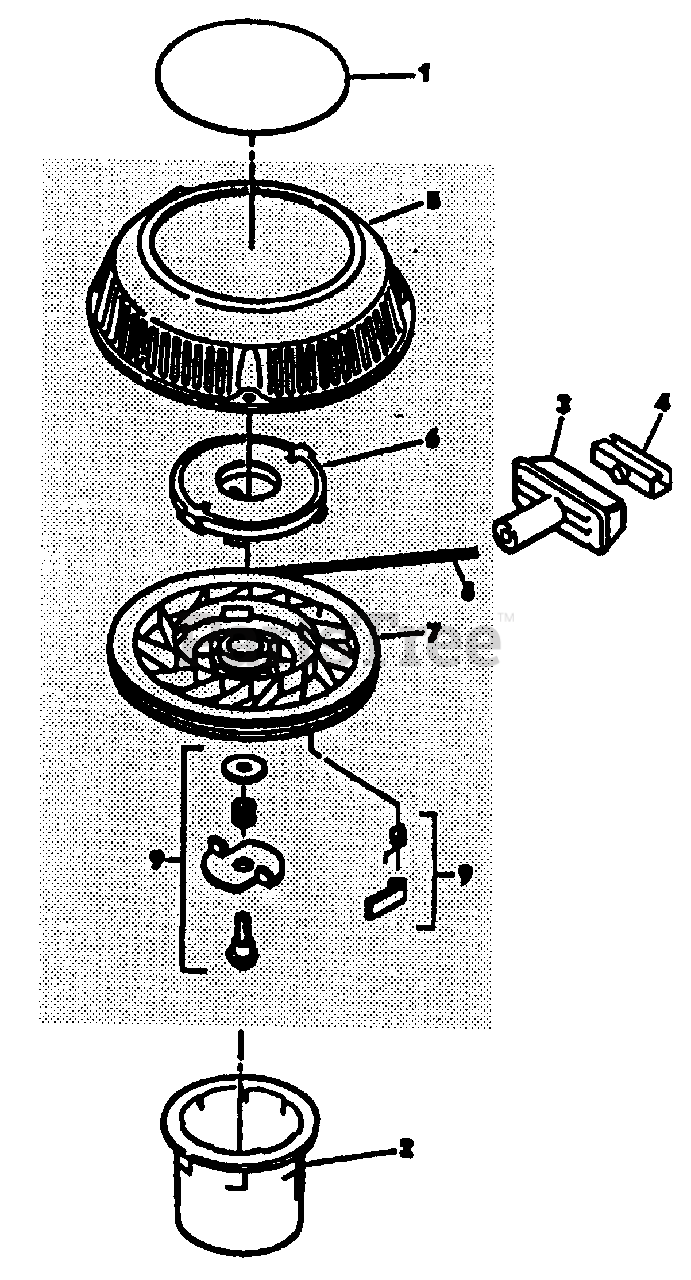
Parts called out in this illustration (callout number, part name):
1	Decal
2	Starter Hub
3	Starter Handle
4	Clip-Rope Insert
5	Starter Housing and Shaft
6	Recoil Spring and Keeper
7	Pulley
8	Rope
9	Dog Kit Assembly
